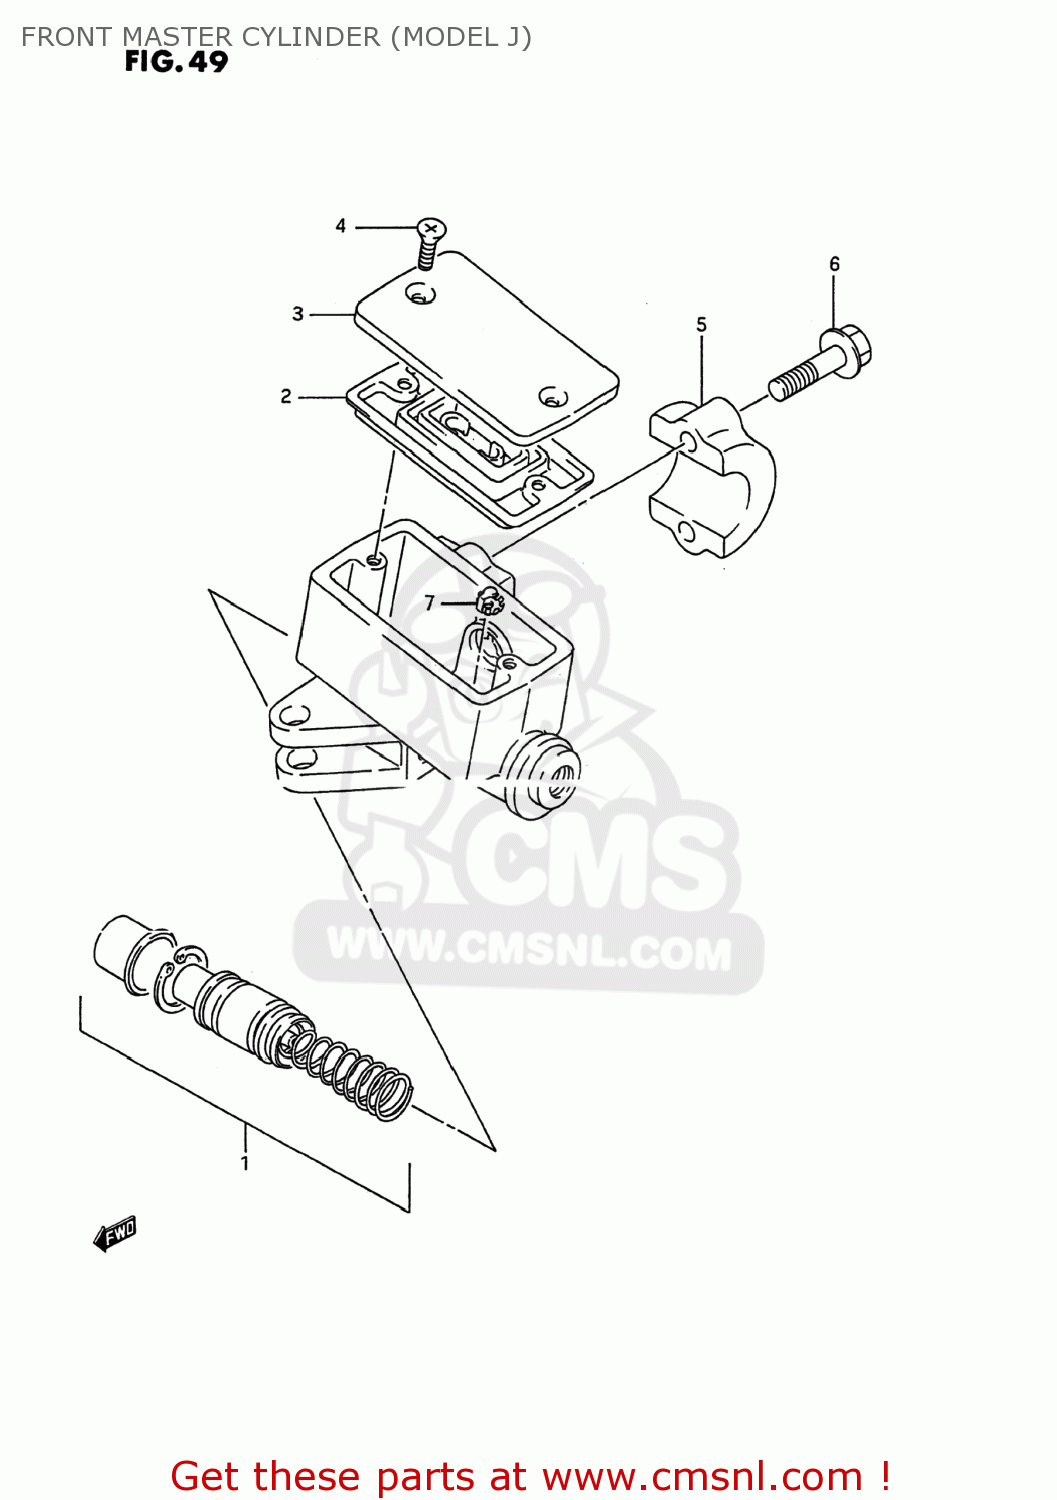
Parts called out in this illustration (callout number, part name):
1	PISTON & CUP SET
2	3
3	CAP
4	SCREW
5	HOLDER
6	BOLT(6X25)
7	PROTECTOR
